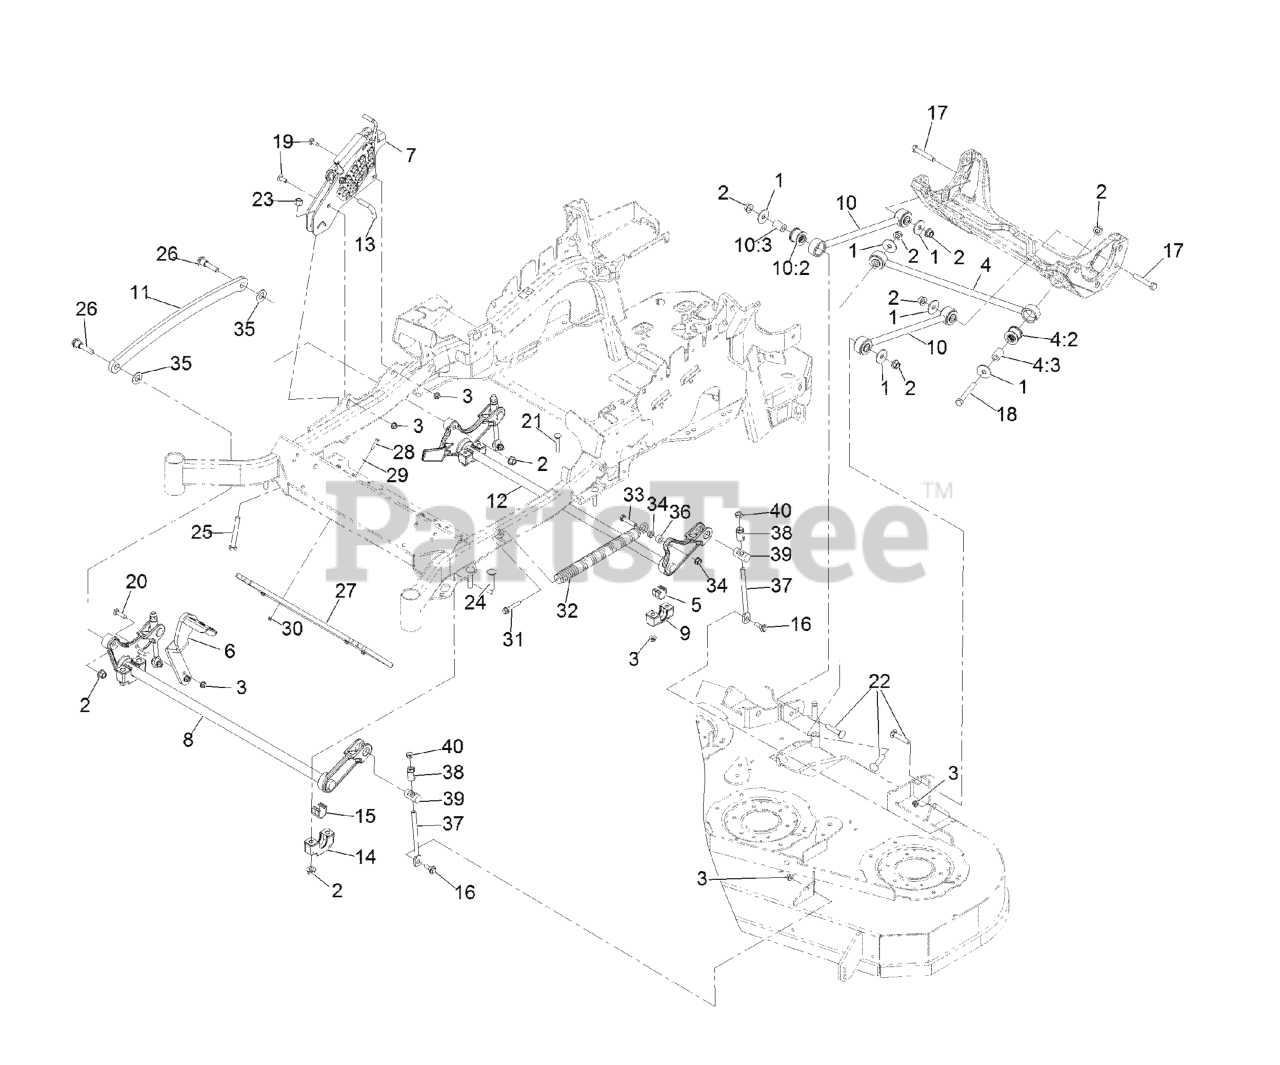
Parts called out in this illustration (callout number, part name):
1	WASHER-THRUST
2	Nut-Lock 1/2-13
3	NUT-HF, NI
4	PANHARD ROD ASM
4:2	BUSHING-SUSPENSION, RUBBER
5	BEARING-CROSS SHAFT, REAR
6	LEVER-FOOT
7	HOC ASM
8	DECKLIFT-FRONT
9	SUPPORT-CROSS SHAFT, BEARING REAR
10	DECK STRUT ASM
10:2	BUSHING-SUSPENSION, RUBBER
11	LINK-LIFT, DECK
12	LIFT-DECK, REAR
13	PIN-HOC
14	SUPPORT-CROSS SHAFT, BEARING
15	BEARING-CROSS SHAFT, FRON
16	SCREW-SHOULDER, HHF
17	SCREW-HH
18	SCREW-HH
19	BOLT-CARR
20	SCREW-CARR
21	Bolt-Carriage 3/8-16 X 2 1/4
22	SCREW-CARR
23	NUT-LOCK, NI
24	Bolt-Carriage 1/2-13 X 2 1/2 Spl Neck
25	BOLT-TAP
26	SCREW-HHF, SHOULDER
27	WEIGHT-TOE BOARD
28	SCREW-HH
29	WASHER-FLAT
31	BOLT-SHOULDER
32	SPRING-EXTENSION
33	SCREW-HH
35	WASHER-FLAT
37	LINK-ADJUSTER, DECK LIFT
38	ADJUSTER-LIFT, DECK
39	TRUNNION
40	NUT-JAM
